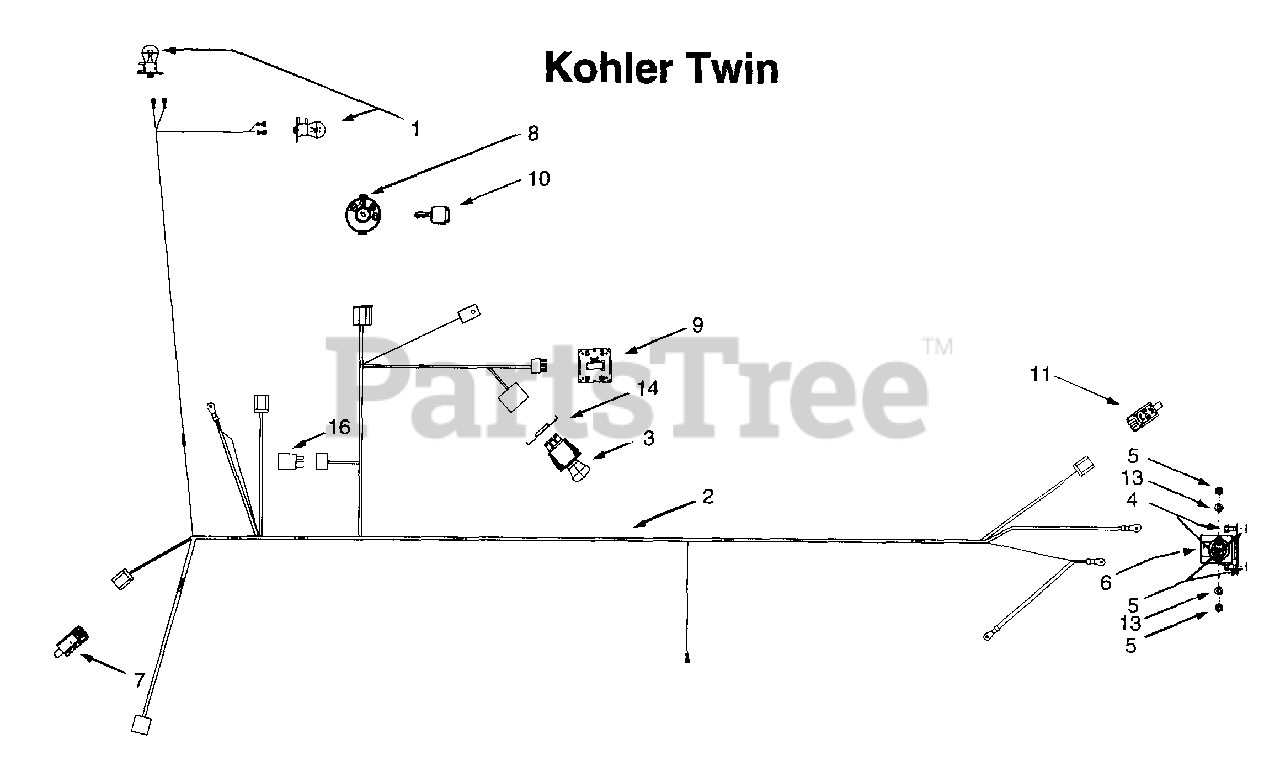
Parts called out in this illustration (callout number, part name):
1	Bulb/Socket Headlight Assembly
2	Wiring Harness
3	Electric PTO Switch
4	Self Tapping Screw, 1/4-20 x .5
5	Hex Nut, 1/4-20
6	Solenoid, 12-volt, 100 Amp
7	Snap Mount Safety Interlock Switch
8	Ignition Switch
9	Indicator Monitor / Hour Meter
10	Ignition Key w/Plastic Cover
11	Safety Plunger Switch
13	Lock Washer, 1/4
14	Retainer Bracket
16	Electric PTO Relay
